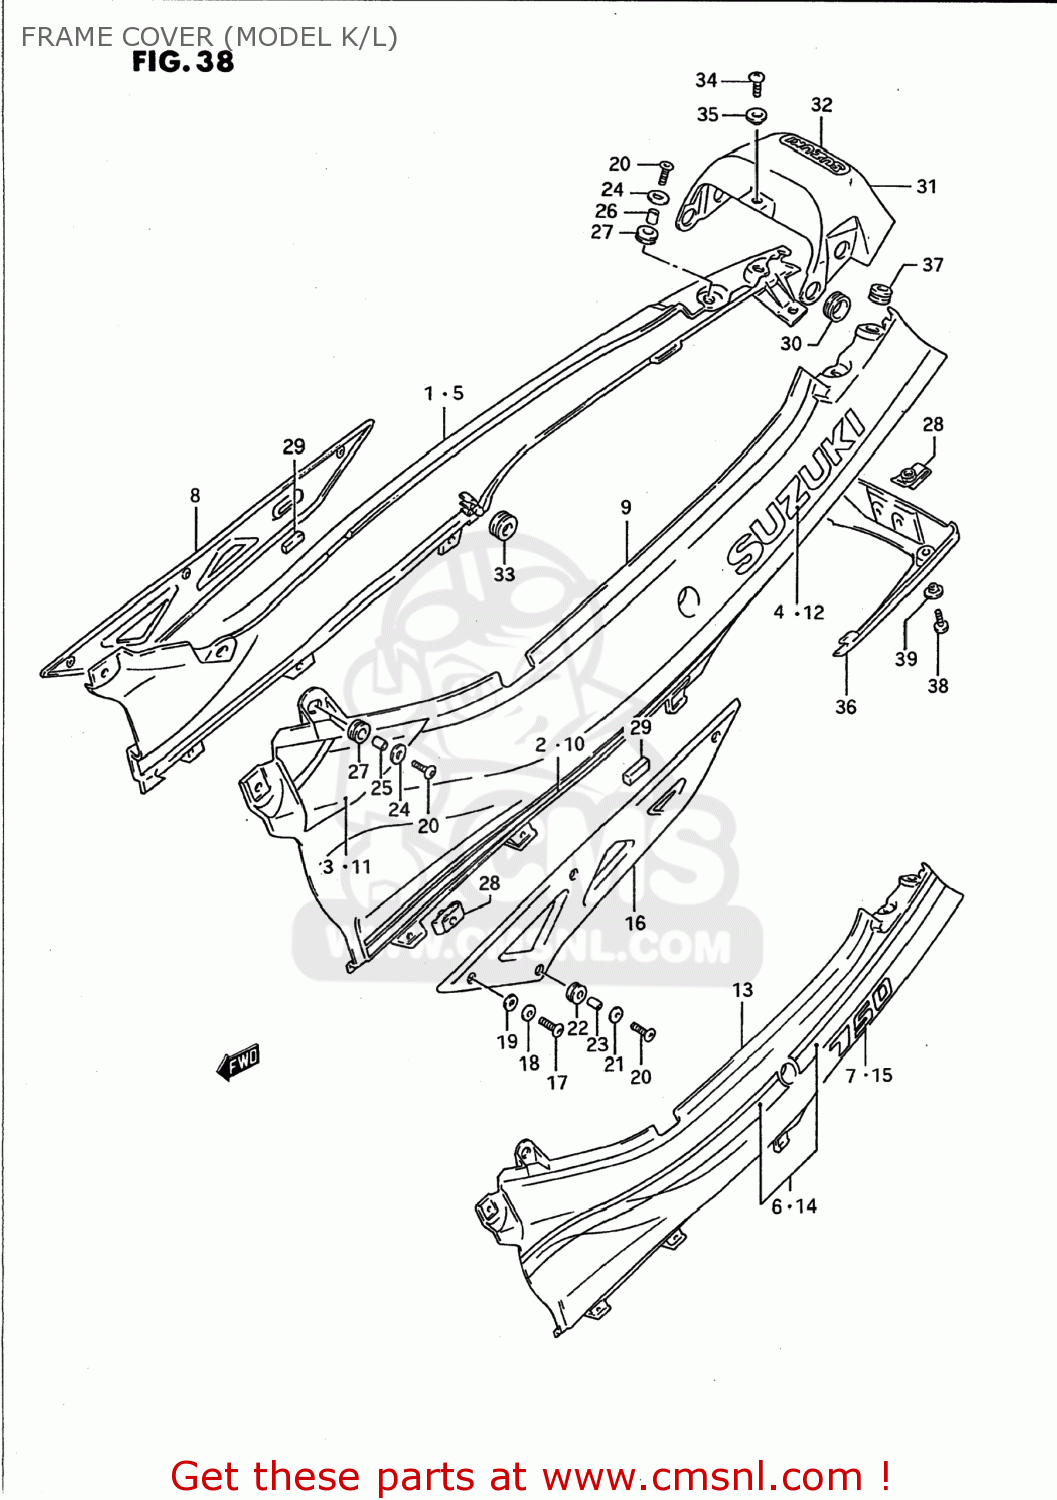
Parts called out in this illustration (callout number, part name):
1	COVER,FRAME,RIGHT
2	TAPE,FRAME COVER STRIPE
3	TAPE,FRAME COVER,RIGHT
4	EMBLEM
5	COVER COMP,FRAME,RIGHT
6	TAPE SET,FRAME COVER,RIGHT
7	EMBLEM,FRAME COVER
8	COVER,FRAME LWR,R
9	COVER,FRAME,LEFT
10	TAPE,FRAME COVER STRIPE
11	TAPE,FRAME COVER,LEFT
12	EMBLEM
13	COVER COMP,FRAME,LEFT
14	TAPE SET,FRAME COVER,LEFT
15	EMBLEM,FRAME COVER
16	COVER,FRAME LWR,L
17	SCREW(6X16)
18	WASHER (6.7X16X1.8)
19	WASHER (5.5X16X1)
20	SCREW(6X16)
21	WASHER(6.5X22X1.6)
22	CUSHION
23	SPACER(6.2X8.3X6.1)
24	WASHER
25	SPACER (6.1X9X9)
26	SPACER(6.1X9X7.5)
27	CUSHION
28	PLATE,FRAME COVER
29	CUSHION,FRAME COVER LWR
30	GROMMET
31	COVER,FRAME,CENTER
32	EMBLEM
33	CUSHION
34	SCREW 6X10
35	WASHER
36	COVER,FRAME RR
37	CUSHION
38	SCREW
39	WASHER
